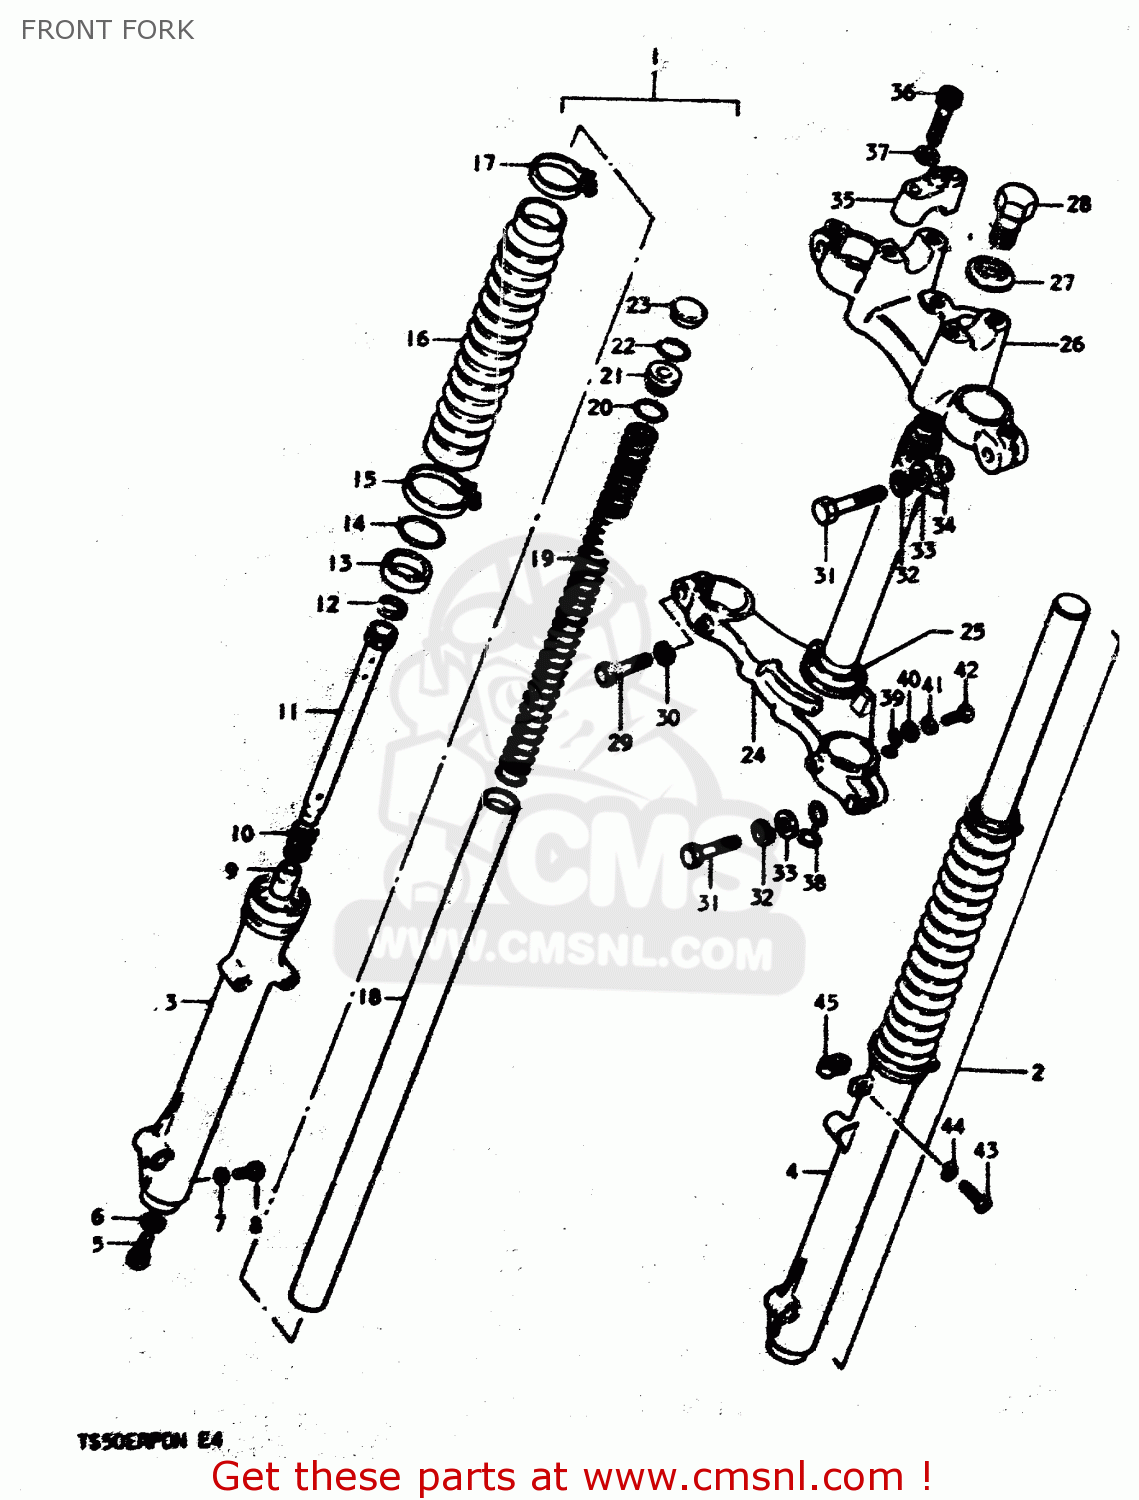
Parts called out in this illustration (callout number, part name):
1	DAMPER ASSY RH
2	DAMPER ASSY LH
3	OUTER TUBE RH
4	OUTER TUBE LH
5	BOLT(8X27)
6	GASKET (NAS)
7	GASKET,DRAIN,PLUG (NAS)
8	BOLT(6X8)
9	PIECE,OIL LOCK
10	SPRING,FORK REBOUND
11	CYLINDER
12	RING
13	OIL SEAL,FRONT FORK
14	CIRCLIP,FORK OIL SEAL
15	CLAMP
16	BOOT
17	BAND,FRONT FORK COVER BOOT
18	INNER TUBE
19	SPRING
20	O RING
21	SEAT,SPRING
22	RING,STOPPER
23	CAP
24	STEM, STEERING
25	RACE,STEERING OUTER LWR
26	HEAD, STEERING STEM
27	WASHER(10.5X30X2.3)
28	BOLT
29	BOLT,M10X1.25X
30	LOCK WASHER
31	BOLT
32	LOCK WASHER
33	WASHER
34	CLIP
35	HOLDER,HANDLEBAR
36	BOLT 8X35
37	LOCK WASHER
38	CLIP
39	CLIP
40	WASHER
41	LOCK WASHER
42	SCREW 6X12
43	SCREW
44	LOCK WASHER
45	CLIP,FR BRAKE CABLE
